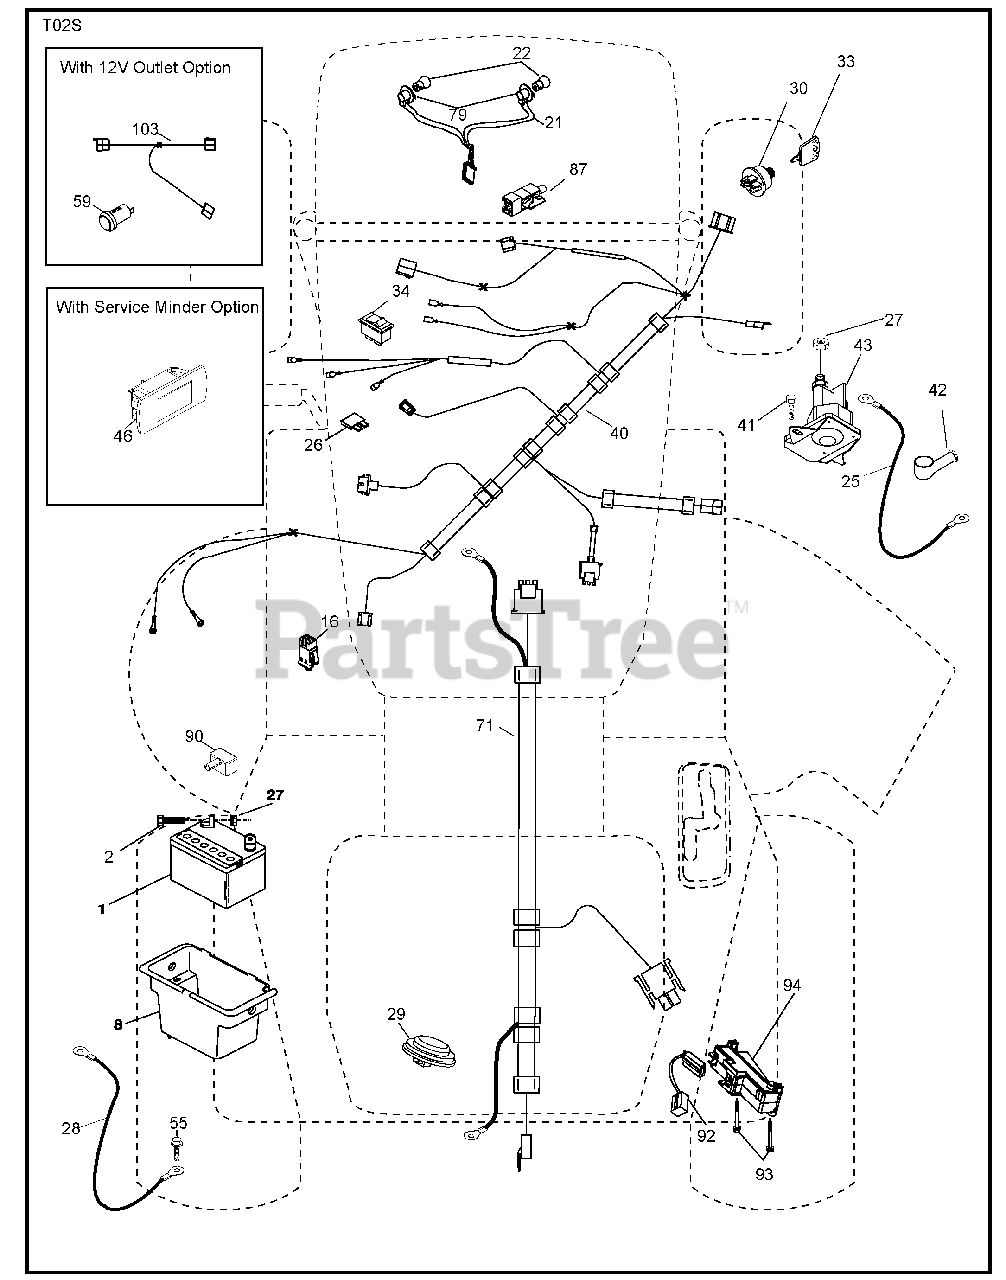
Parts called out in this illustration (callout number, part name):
1	Battery
2	Bolt Hex Hd 1/4-20 unc x 3/4
8	Box Battery
16	Switch Interlock
21	Harness Socket Light
22	Bulb, Light #1156
25	Cable Starter 6 Ga. BL/Red 14.5
26	Fuse
27	Nut Keps Hex 1/4-20 unc
28	Cable Ground 18" Rear Battery Blk 6 Ga.
29	Switch Seat
30	Switch Ign
33	Key/Chain
34	Switch Light/Reset
40	Harness Ign
41	Screw 1/4-20 unc x 1/2
42	Cover Terminal Red
43	Solenoid
55	Screw 5/16-18 x 3/4
71	Harness Ign. Chass.
79	Socket Asm. Bulb
87	Switch Interlock Clutch
90	Cover Terminal
92	Harness Pigtail Reverse Switch
93	Screw Plastic 10-14 x 2.0
94	Modual Reverse ROS
